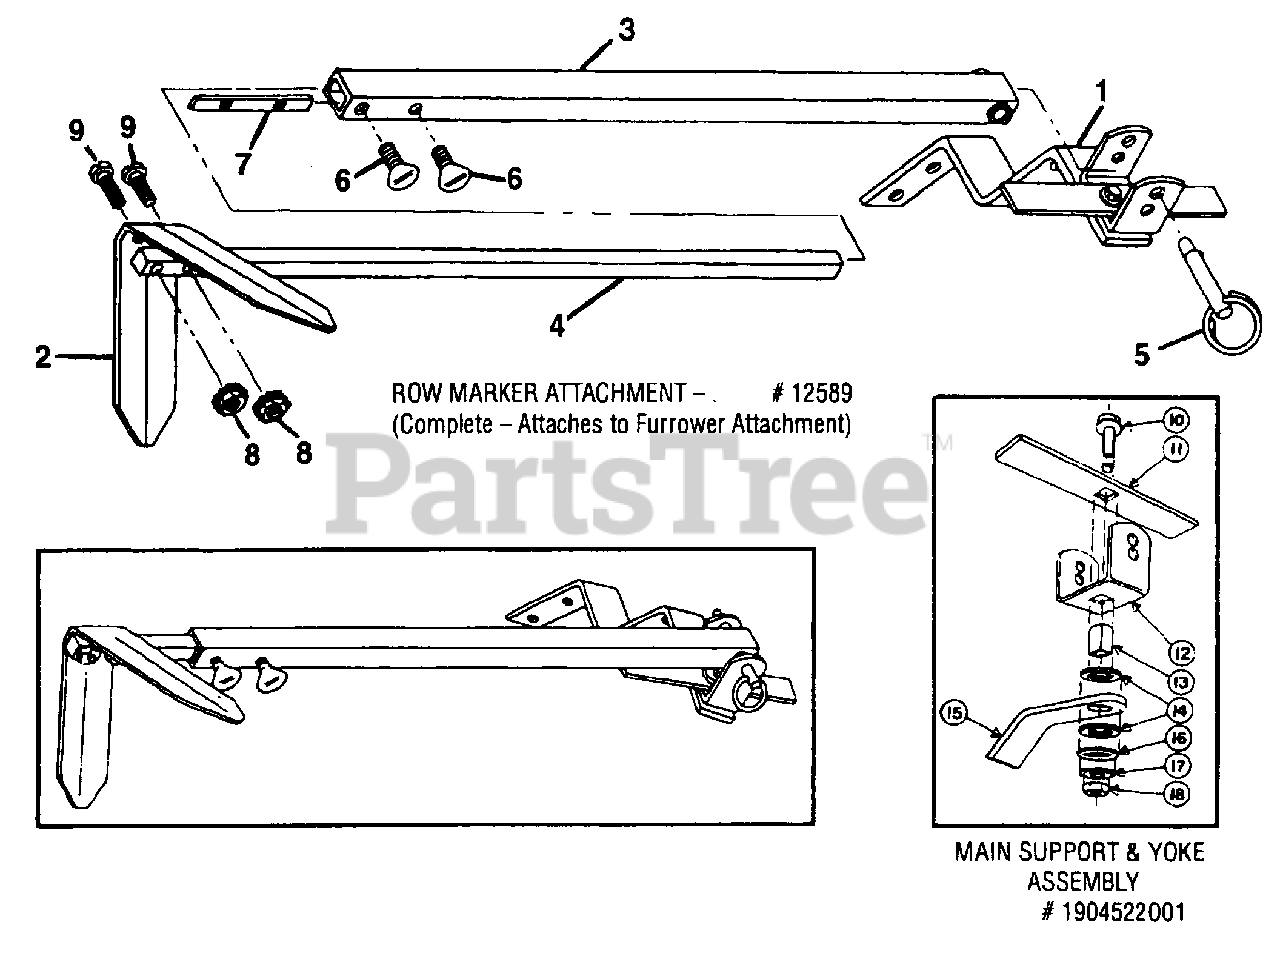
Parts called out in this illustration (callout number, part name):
1	Main Support & Yoke Assy- complete.
2	Marker Blade-blade only
3	Marker Arm-main arm
4	Marker Arm-extension arm with stop pin
5	Hitch Pin
6	Thumbscrew - 1/4-20 x 1/2
7	Nut Bar
8	Nut-hex, 10-24
9	Screw-round hd., 10-24 x 1
10	Screw- hex flanged locking, 3/8-16 x 1-1/2
11	Stop Bar
12	Yoke
13	Tube Key-square
14	Washer-friction
15	Main Support
16	Washer-square hole
17	Washer-disc spring
18	Nut-hex 3/8-16
